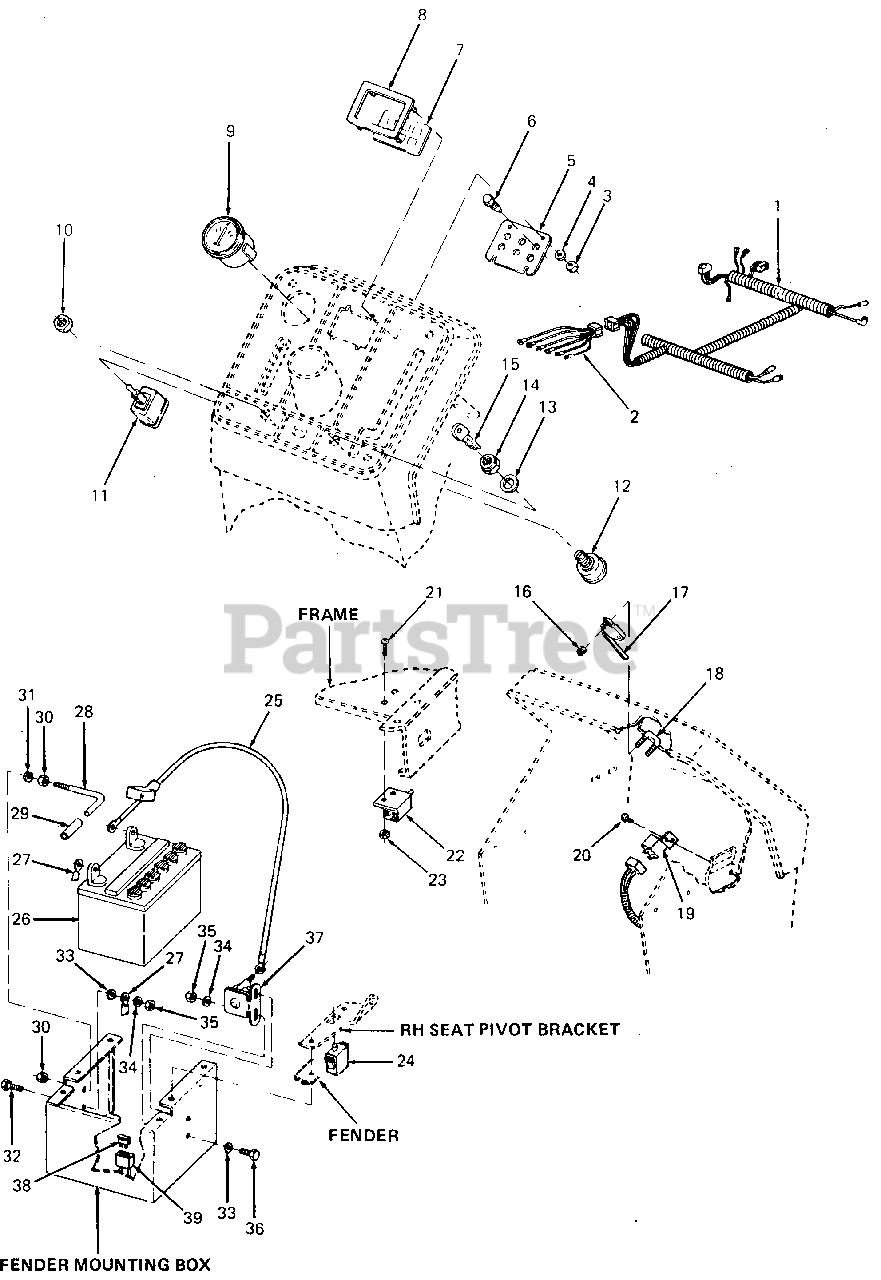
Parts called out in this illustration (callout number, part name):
1	Harness, Wire
2	Harness, Indicator Wire
3	Nut, Self-Threading Pal
4	Washer, Rubber, .18 X .50 X .06 Thk
5	Plate, Indicator
6	Lamp, Indicator
7	Label, Indicator
8	Bezel, Light
9	Ammeter
10	Nut, Hex, 1/2-27 X .100 Thk
11	Switch, PTO
12	Switch, Ignition Key
13	Washer, Flat
14	Nut, Ignition Switch
15	Key, Ignition (Set of 2)
16	Nut, Hex Insert Lock, #4-40
17	Switch, Micro
18	Screw, Switch
19	Relay
20	Screw, Pan Hd Tapp, #12 X .50 Lg
21	Screw, #10-24 X .50 Lg
22	Switch, Double Poled Plunger
23	Nut, Hex Center Lock, #10-24
24	Switch, Interlock
25	Wire, Positive Battery
26	Battery, 12 Volt
27	Wire, Ground, 11.5 Lg
28	Pin, Locking
29	Fuel Line, 2 in. Long
30	Nut, Hex, 5/16-24 GR5
31	Washer, Lock, 5/16
32	Screw, Hex Cap, 1/4-20 X .62 Lg GR5
33	Washer, Int Ext Lock, 1/4 X 3/4
34	Washer, Flat, .281 X .73 X .063 Thk
35	Nut, Hex Patch Lock, 1/4-20
36	Screw, Hex Cap, 1/4-20 X .50 Lg GR5
37	Solenoid, 12 Volt
38	Fuse, Auto Type, 20 Amp
39	Fuse Holder
